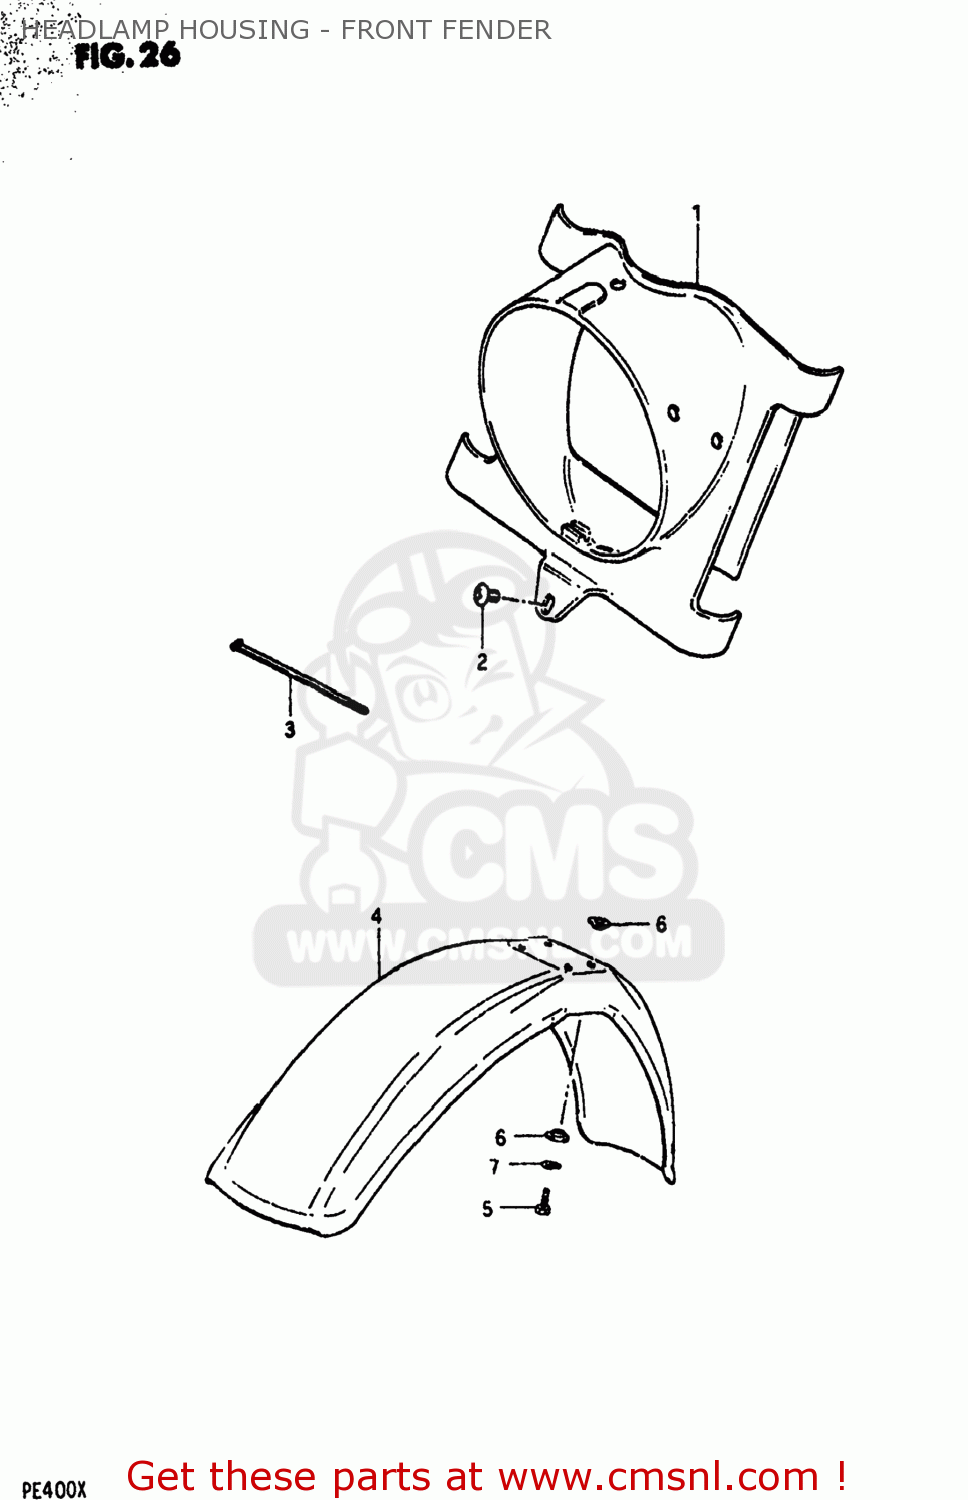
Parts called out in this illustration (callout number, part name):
1	HOUSING,HEADLAMP
2	SCREW
3	CLAMP
4	FENDER,FRONT
5	BOLT, UPPER
6	WASHER
7	LOCK WASHER
